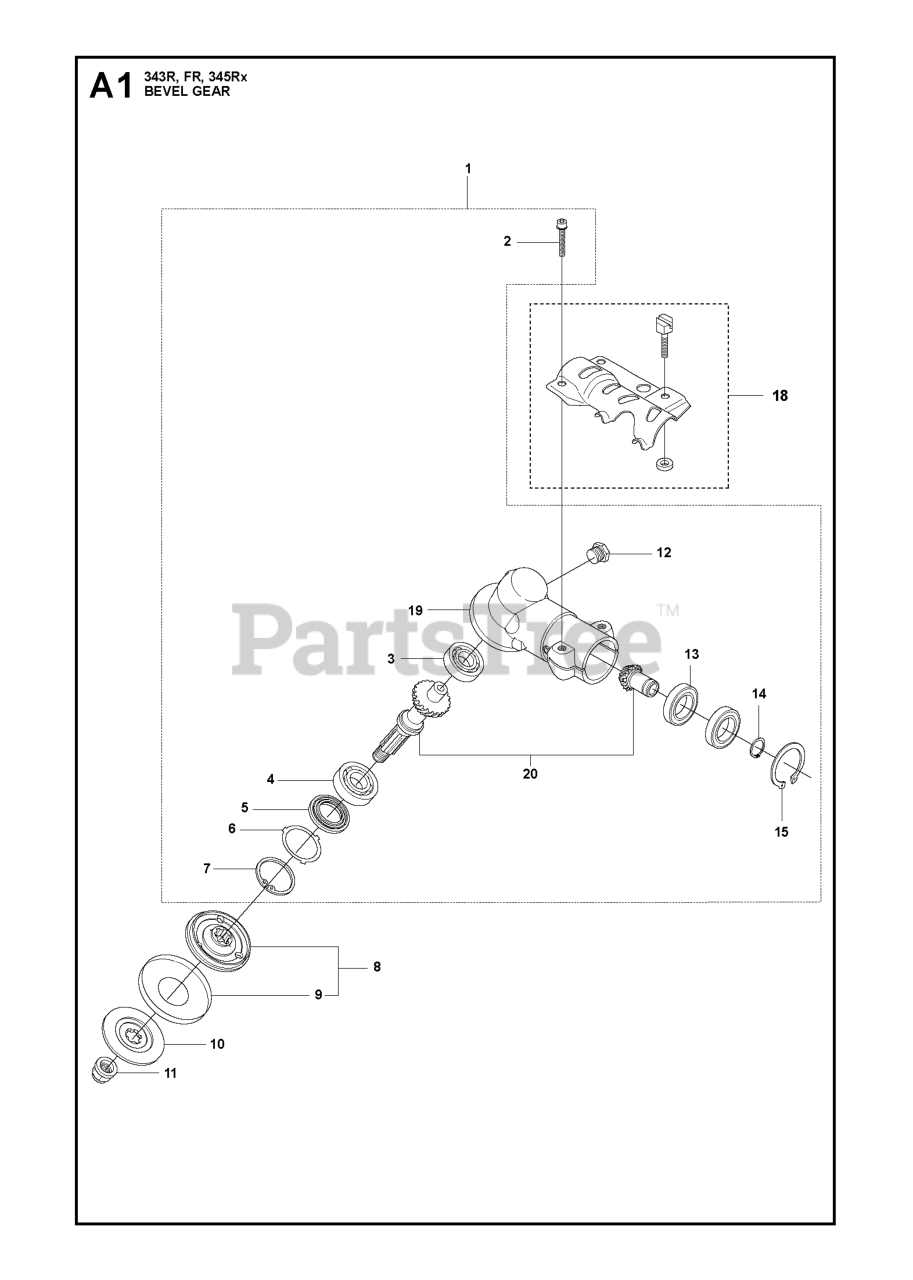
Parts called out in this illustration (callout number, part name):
1	GEAR ASSY
3	BALL BEARING
4	BALL BEARING
7	RETAINING RING SGH 35
8	RP CARRIER
9	RP TUBE INSERT
10	SUPPORT FLANGE
13	BALL BEARING
14	RETAINING RING SGA 15
15	RETAINING RING
18	SPACING SLEEVE
19	GEAR HOUSING
20	SPARE PARTS KIT
